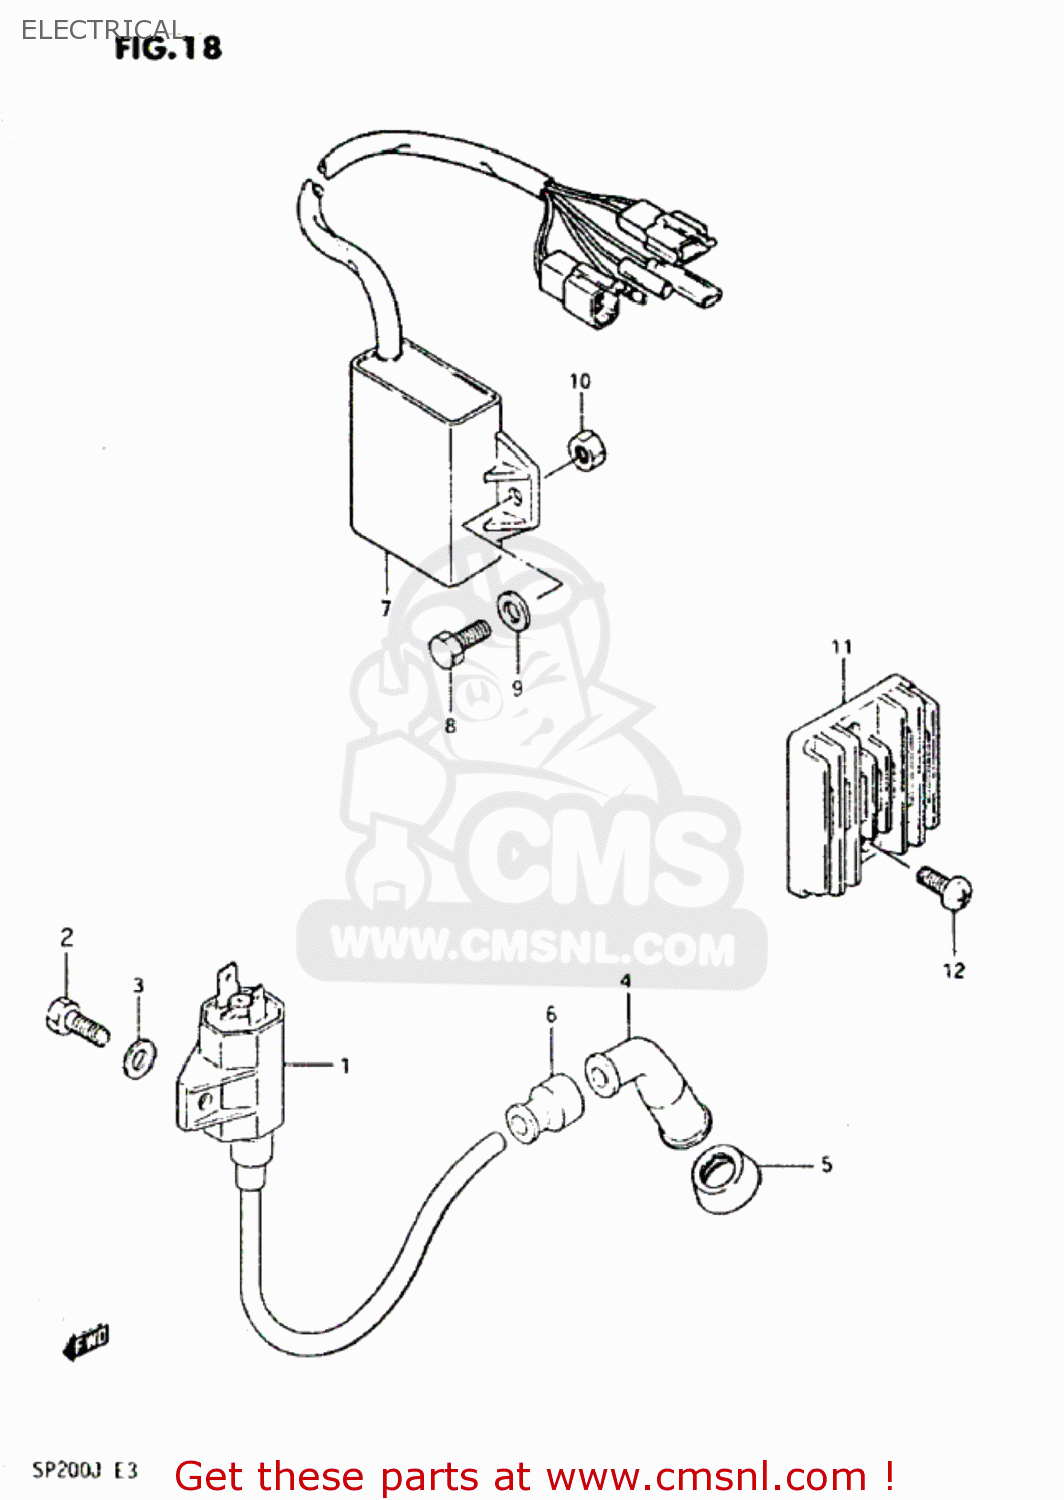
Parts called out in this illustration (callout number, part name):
1	COIL ASSEMBLY,IGNITION
2	BOLT
3	WASHER, LOWER
4	CAP,SPARK PLUG
5	SEAL,SPARK PLUG CAP
6	SEAL,SPARK PLU
7	CDI UNIT
8	BOLT
9	WASHER, LOWER
10	NUT
11	RECTIFIER ASSY
12	SCREW
